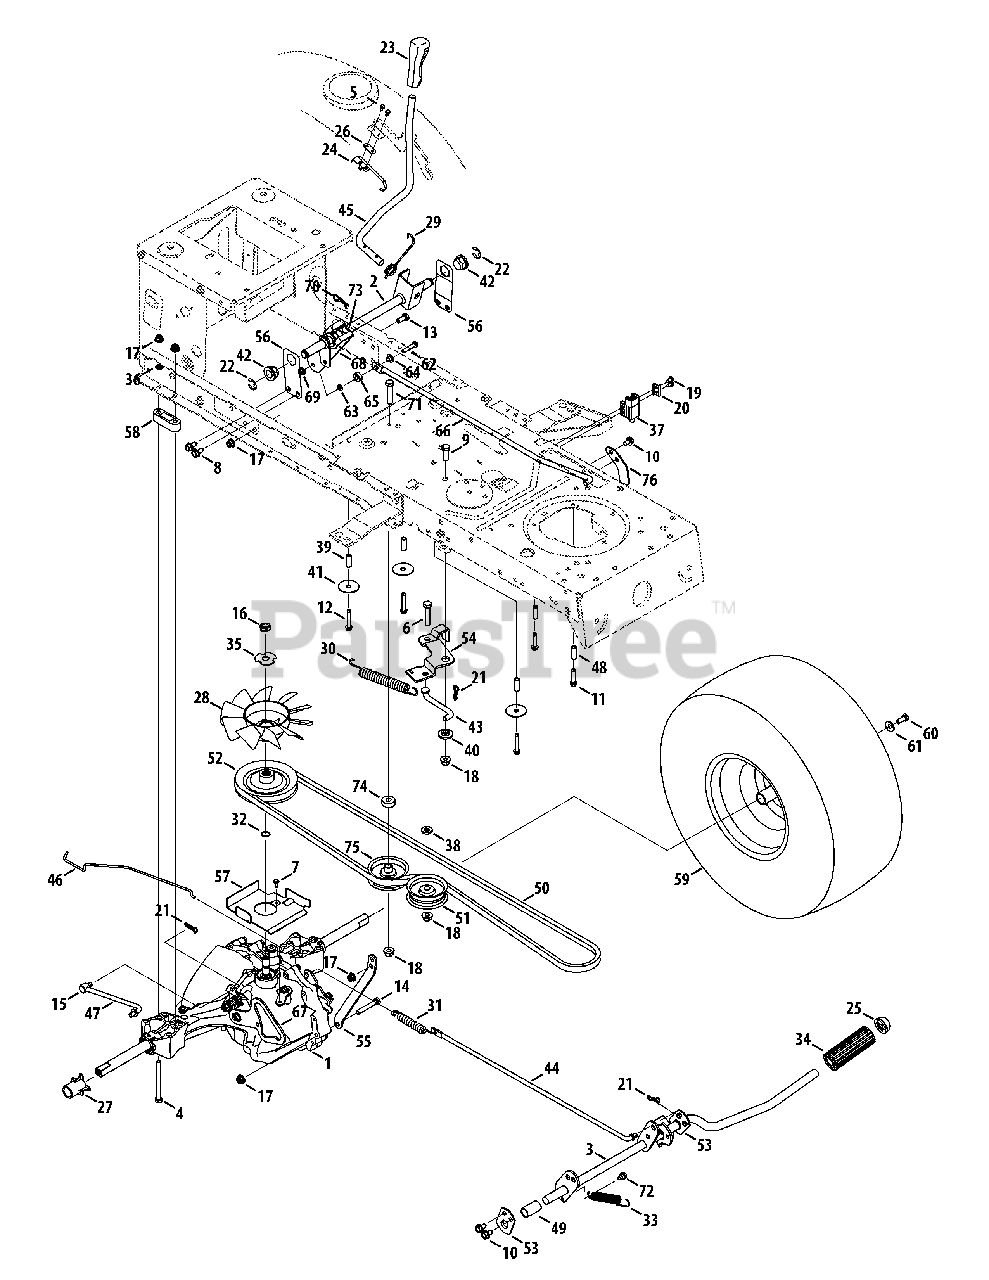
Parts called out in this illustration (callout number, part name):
1	Hydro Transmission
1	Hydro Transmission, 18" Tires
2	Hydro Handle Control Assembly
3	Hydro Pedal Assembly
4	Hex Screw, 5/16-18 x 3.5
5	Screw, #8-18x0.500
6	Hex Screw, 3/8-16x1.75
7	Screw, #10-16x0.500
8	Screw, 5/16-18x.750
9	Hex Screw, 3/8-16x1.00
10	Screw, 5/16-18x0.625
11	Screw, 1/4-20x1.250
12	Screw, 1/4-20 x 1.75
13	Hex Screw, 5/16-18x.75
14	Screw, 5/16-18 x 2.00
15	Ferrule, 5/16-24 X .312 DIA.
16	Jamlock Nut, 1/2-20
17	Flangelock Nut, 5/16-18
18	Flangelock Nut, 3/8-16
20	Plate Switch
21	Cotter Pin, Bow Tie
22	E Ring, .625 DIA
23	Handle Grip
24	Hydro Spring Switch
25	Push Cap, 5/8
26	Insulator Plate Nut
27	Sleeve, .765 ID X 2.11 LG
28	Hydro Fan
29	Torsion Spring
30	Extension Spring, .75 DIA. X 6.02
31	Extension Spring, .59 OD X 4.00 LG
32	Wire Ring
33	Extension Spring, .63 DIA X 4.95 LG
34	Foot Pad, 4.0
35	Lock Washer, TRANS HYDRO
36	Lock Washer, 5/16 EXT TOOTH
37	Switch Interlock
38	Flat Washer, .407X.812X.135:HT
39	Spacer, .260 x .372 x 1.420
40	Shldr Spacer, 1.375 ID X .380 x 1.54
41	Flat Washer, .350 x 1.59 x .062
42	Hex Flange Bearing
43	Declutching Rod
44	Brake Rod
45	Hydro Control Handle
46	Hydro Bypass Rod
47	Hydro Control Rod
48	Spacer, .260 x .375 x 1.030 LG
49	Spacer, .640 ID X .76 OD X 1.60
50	V Belt, 4L SEC X 84.17
51	Flat Idler Pulley 2.75 OD
52	Input Pulley
53	Support Pedal Bracket
56	Handle Bracket
57	Belt Support Bracket
58	Spacer, T-Axle
59	Wheel, 20 x 8 x 8 - Grey
59	Wheel, 20 x 8 x 8 - Yellow
59	Wheel, 18 x 9.5 x 8 Grey
60	Hex Screw, 5/16-24 x .750
61	Bell Washer, .340 x .872 x .060
62	Hex Screw, 1/4-20 x 1.25
63	Flat Washer, .281 x .500 x .063
64	Shoulder Spacer, .375 x .625 x .20
65	Ball Bearing, .25 x .6875 x .25
66	Hydro Rod, RTN
67	Cam Bracket, RTN
68	Pivot Bracket, RTN
69	Nut, Flange Lock, 1/4-20, GrF
70	Click Pin, .092 x 1.64 LG
71	Hex Screw, 3/8-16 x 2.00
72	Shoulder Screw, 1/4-20 x 0.50
73	Hex Flange Bearing, .628 ID
74	Spacer, .406 ID x 1.00 OD x .38
75	V Pulley 3.06 OD
76	Stop Pedal Plate
